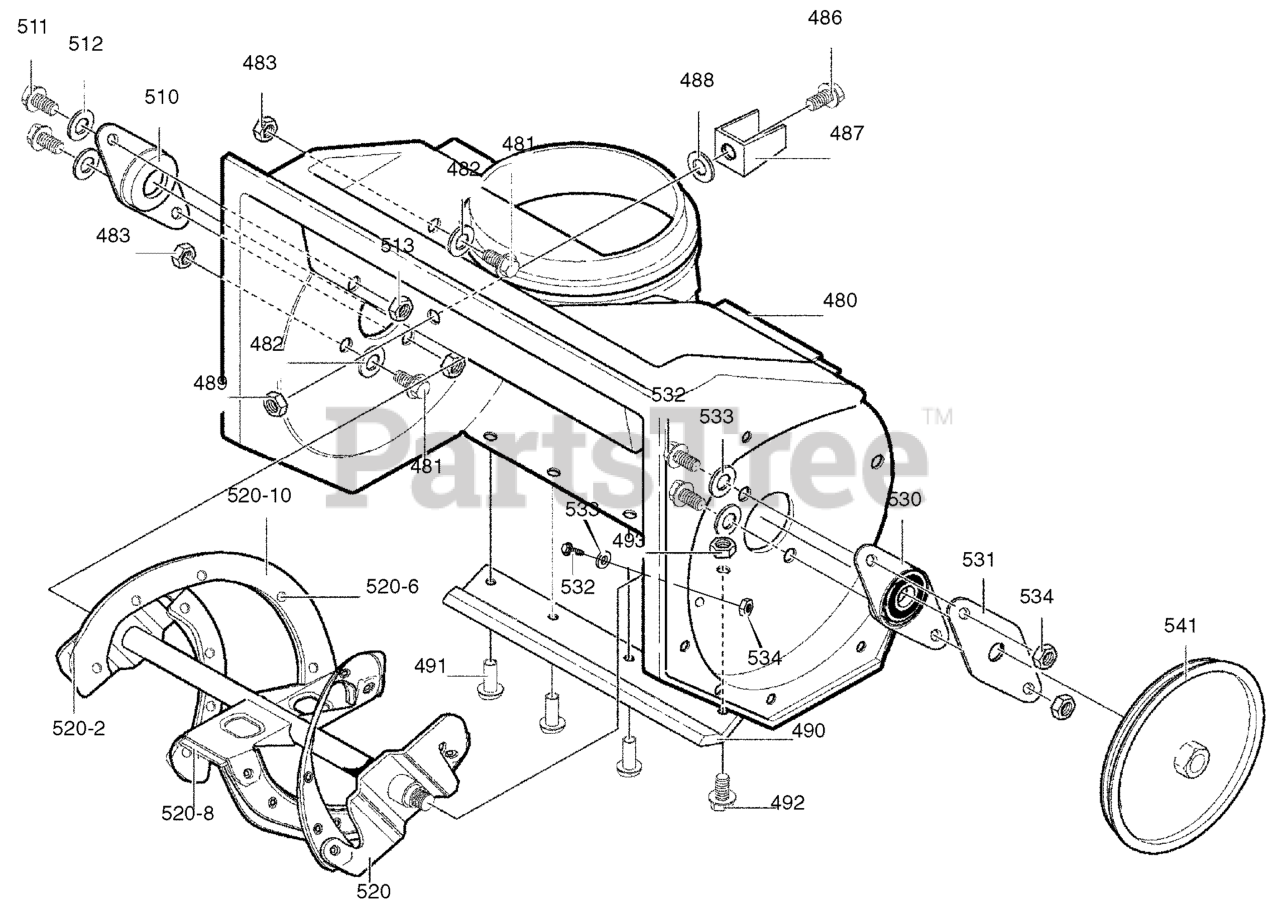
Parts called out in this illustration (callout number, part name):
480	HOUSING, ASSY
481	SCREW, 1/4-20X.75
482	WASHER, FLAT .281X.63X.065
483	NUT, HEX 1/4-20 YZ
486	SCREW, 1/4-20X.63
487	BRACKET, STOP
488	WASHER, FLAT .333X.87X.119
489	NUT, 1/4-20 HEX NYLOCK
490	BLADE, SCRAPER
491	RIVET, OVSET
492	SCREW, 1/4-20X.75
493	NUT, 1/4-20 YZ
510	BEARING, FLANGE
511	SCREW, 1/4-20X1.00
512	WASHER, FLAT .281X.63X.065
513	NUT, 1/4-20 YZ
520	AUGER, ASSY
520-2	BLADE, AUGER
520-6	RIVET
520-8	BLADE, CENTER
520-10	AUGER & BLADE SUPPORT
530	BEARING & PLATE ASSY
531	PLATE, RETAINER
532	SCREW, 1/4-20X.63
533	WASHER, FLAT .281X.63X.065
534	NUT, 1/4-20
541	PULLEY
